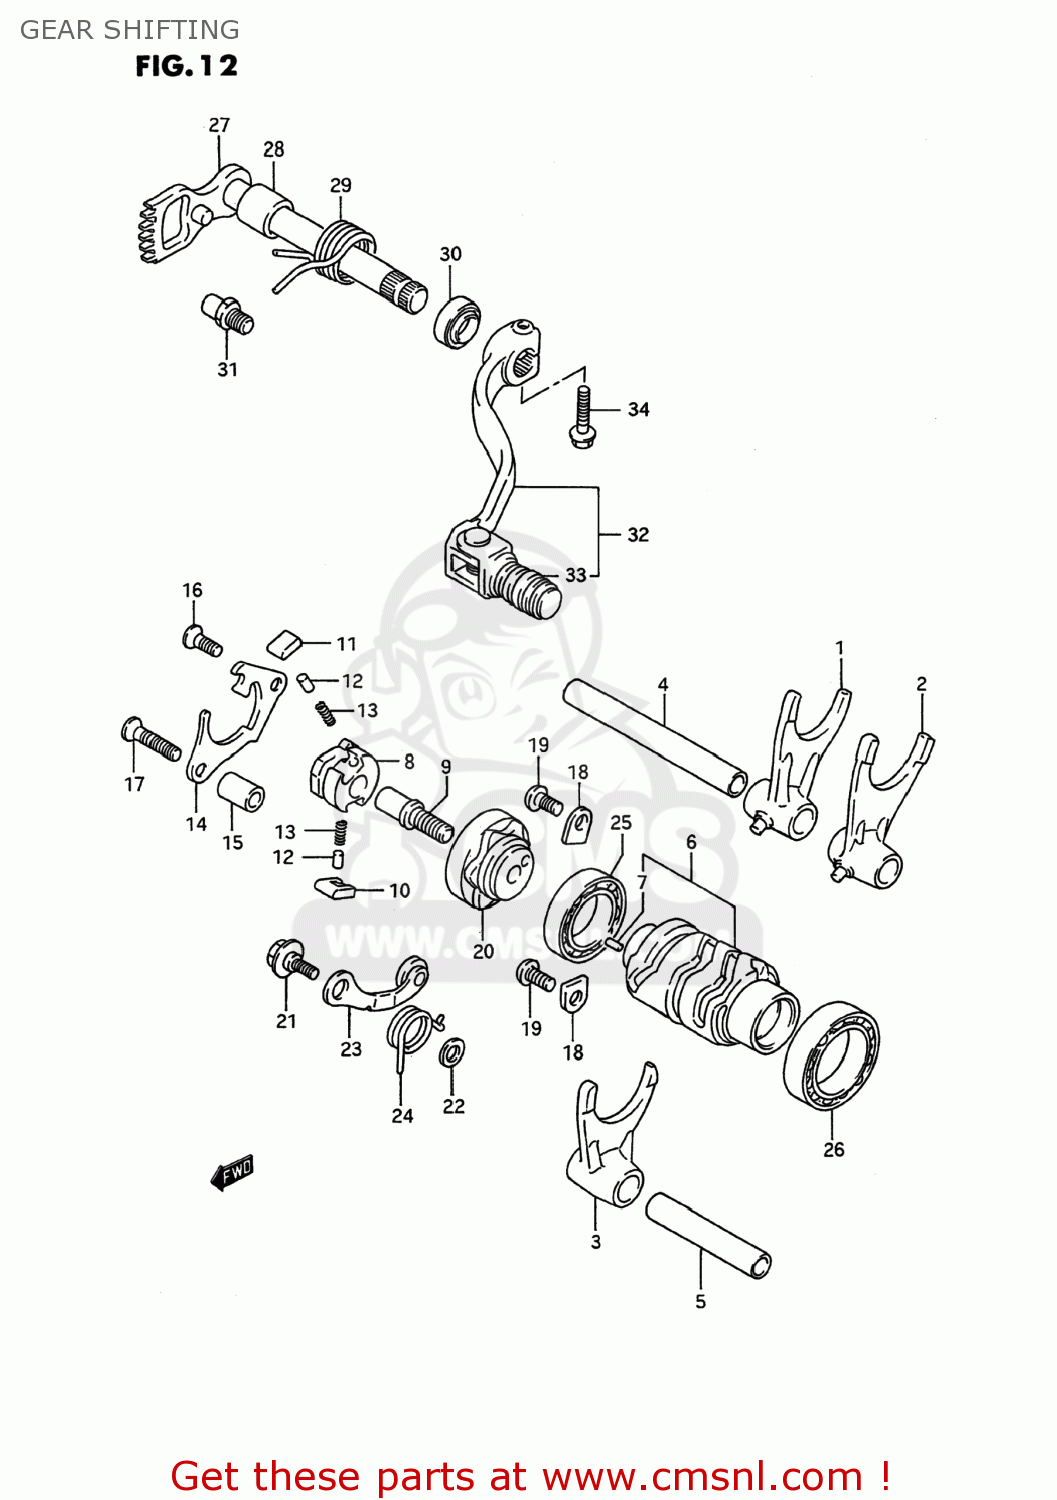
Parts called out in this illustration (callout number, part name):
1	FORK,GEAR SHIFT NO.1
2	FORK,GEAR SHIFT NO.2
3	FORK,GEAR SHIFT NO.3
4	SHAFT,GEAR SHIFT FORK
5	SHAFT,GEAR SHIFT FORK
6	CAM,GEAR SHIFT
7	PIN
8	GEAR,GEARSHIFT CAM DRIVE
9	PIN,SHIFT CAM DRIVEN GEAR
10	PAWL,GEAR SHIFT NO.1
11	PAWL,GEAR SHIFT NO.2
12	PIN(5X8)
13	SPRING
14	LIFTER,GEAR SHIFT POLE
15	SPACER(6.2X12X18)
16	SCREW
17	SCREW
18	RETAINER
19	SCREW
20	PLATE,GEAR SHIFT CAM STOPPER
21	BOLT(6X14.3)
22	WASHER
23	STOPPER,SHIFT CAM
24	SPRING
25	BEARING
26	BEARING(30X37X12)
27	SHAFT,GEAR SHIFT
28	SPACER(14X20X17.5)
29	SPRING
30	SEAL,OIL(14X22X6)
31	STOPPER,GEAR SHIFT CAM
32	LEVER ASSEMBLY,GEAR SHIFTING
33	RUBBER,GEAR SHIFT PEDAL
34	BOLT
